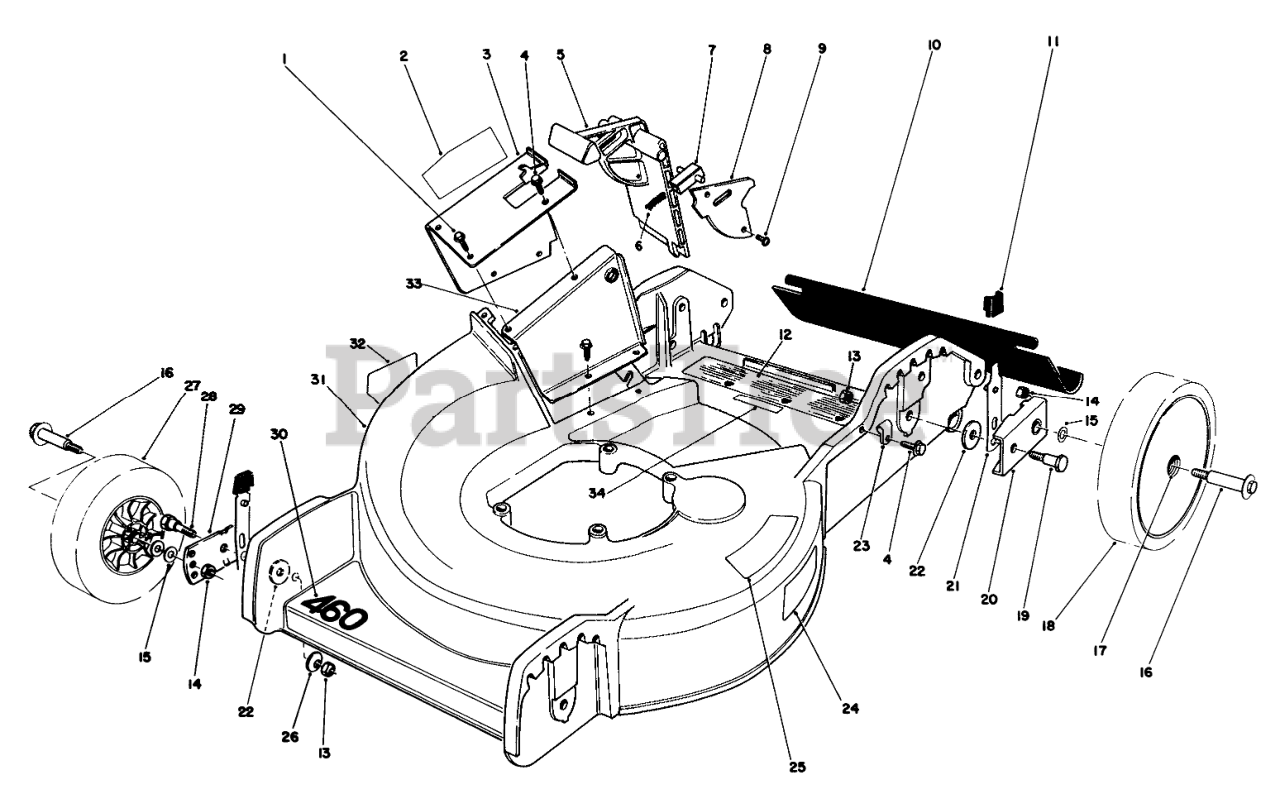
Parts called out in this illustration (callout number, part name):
1	SCREW
2	OBS DANGER DECAL FR/E/GER
3	Tunnel-Outer (Incl. Ref. #2)
4	SCREW
5	Door Mulching
6	SPRING-COMPRESSION, LATCH
7	Door Latch
8	Cover Door
10	SHIELD - TRAILING
11	KNOB-ARM
12	DECAL-DANGER
13	NUT-LOCK, NI
14	Nut
15	WASHER
16	BOLT-WHEEL
17	BUSHING
18	Wheel & Tire Assembly (Incl. Ref. #17)
19	PIVOT SCREW
20	PIVOT ARM ASM
21	SPRING ARM ASM
22	PIVOT WASHER
23	CLAMP-CABLE
24	Decal-Place Foot Here
25	STEP PAD DECAL
26	WASHER-BELLEVILLE
27	Wheel & Tire Assembly (Inc. Ref. #17)
28	5/16-18 PIVOT SCREW
29	PIVOT ARM ASSY
30	Decal-460
31	HSG & CARTON
32	DECAL-DANGER
33	Tunnel-Inner
34	Decal
